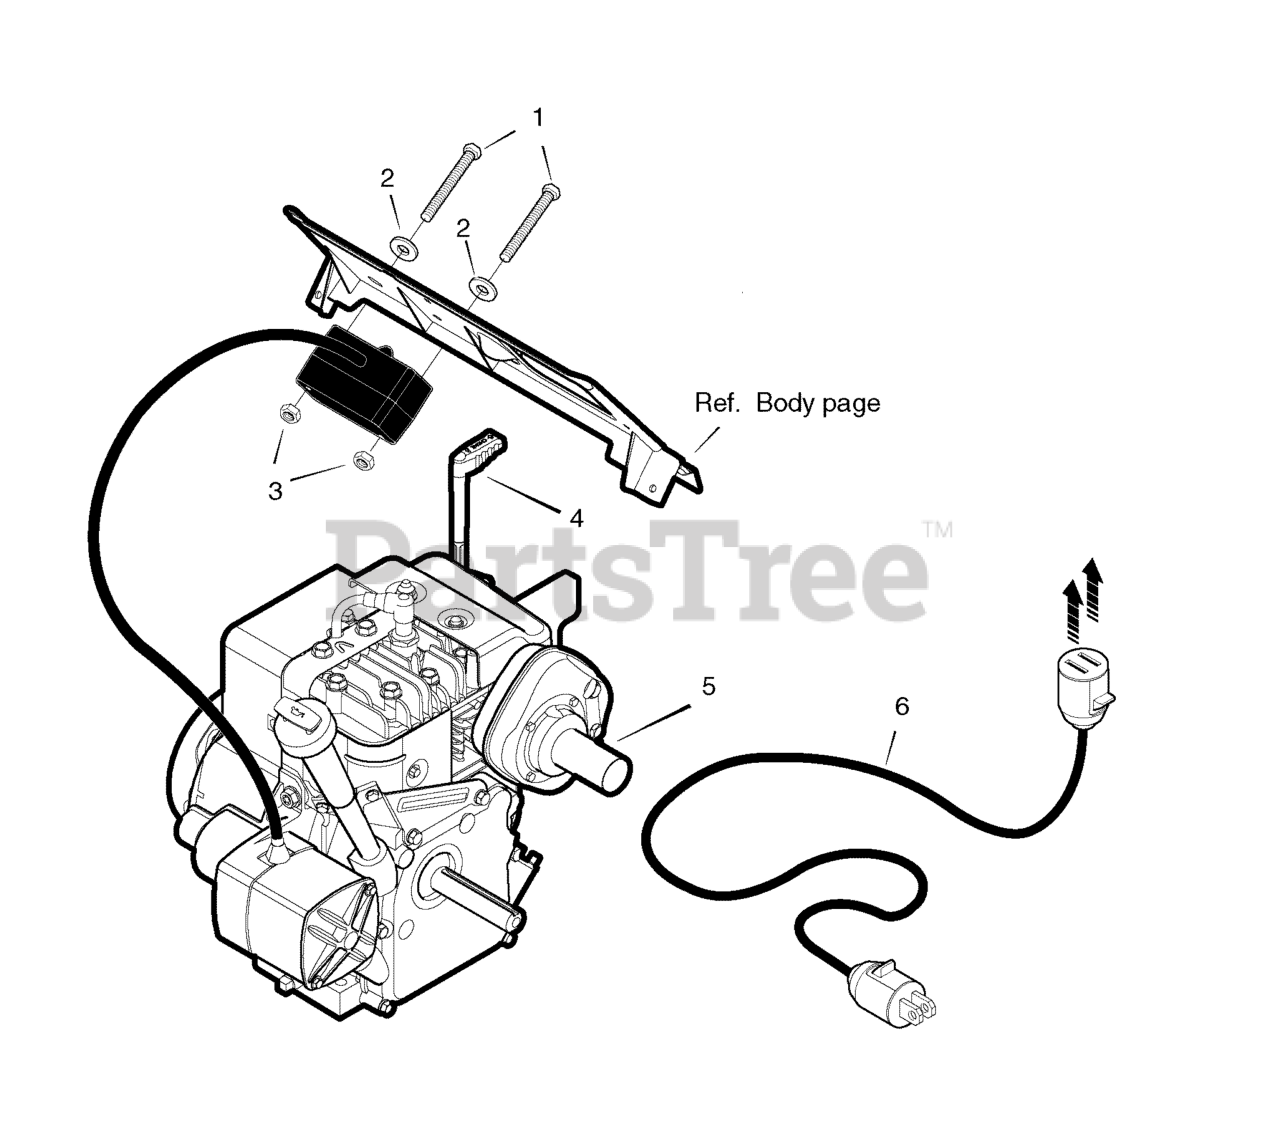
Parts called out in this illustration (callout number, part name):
1	Screw, No. 8-32 x 3.00
3	Nut, Keps No. 8
4	Lever, Choke *
5-1	Muffler *
5-2	Gasket, Muffler *
5-3	Bolt, Muffler *
5-4	Washer, Split Lock
5-5	Nut, Hex 5/16-18
5-6	Bolt, Hex 5/16-18
6	CORD, Electric, 10FT. 110V
